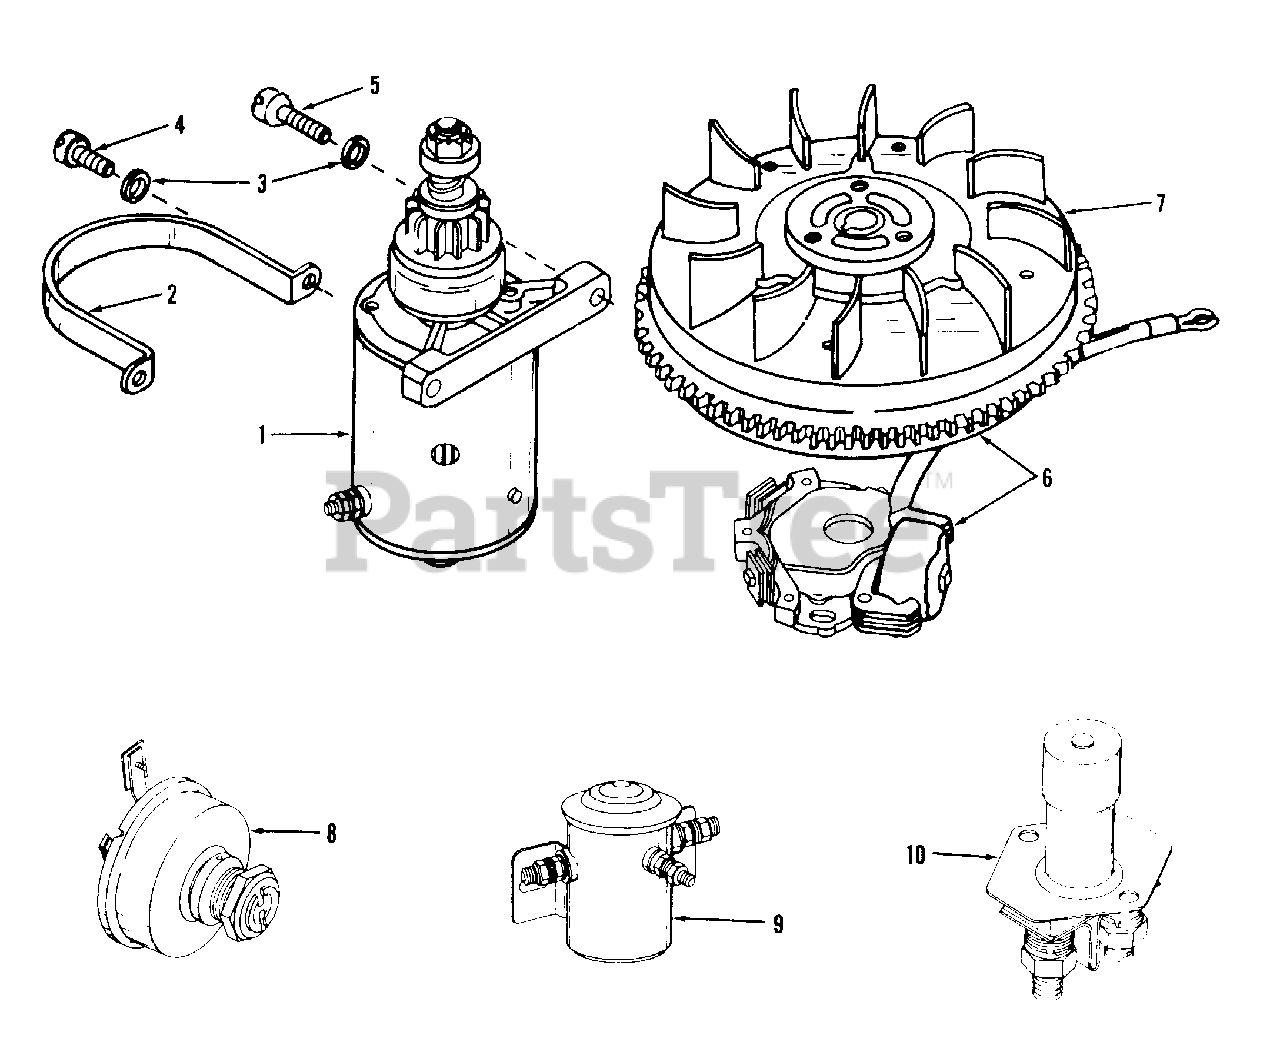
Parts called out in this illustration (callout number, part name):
1	"Motor, Electric
2	Bracket, Motor mounting
3	Lockwasher
6	Magneto, Alternator
8	Switch, Starter
9	Solenoid
